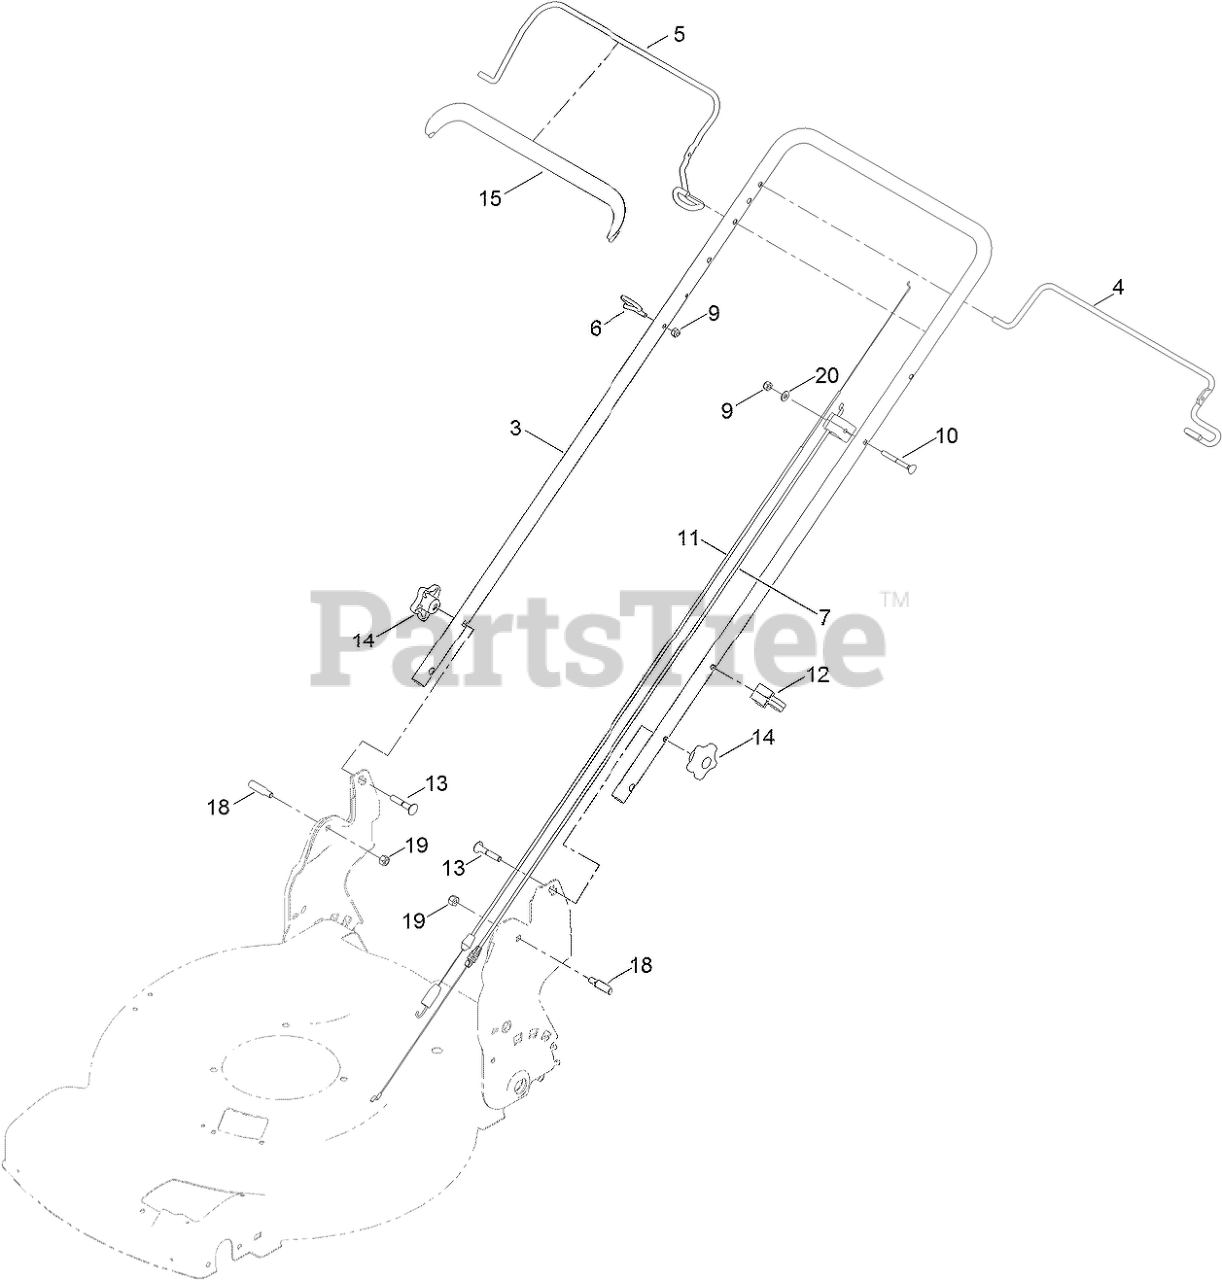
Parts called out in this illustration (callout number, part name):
4	BAIL-TRACTION
5	BAIL-BRAKE
6	GUIDE-ROPE
7	CABLE-BRAKE, HP
9	NUT-LOCK, NI
10	SCREW-HANDLE
11	CABLE-TRACTION
12	GUIDE-CABLE
13	SCREW-CARR
14	KNOB-HANDLE
15	COVER-BAIL
18	BOLT-SHOULDER
19	NUT-LOCK, NI
20	WASHER-FLAT
